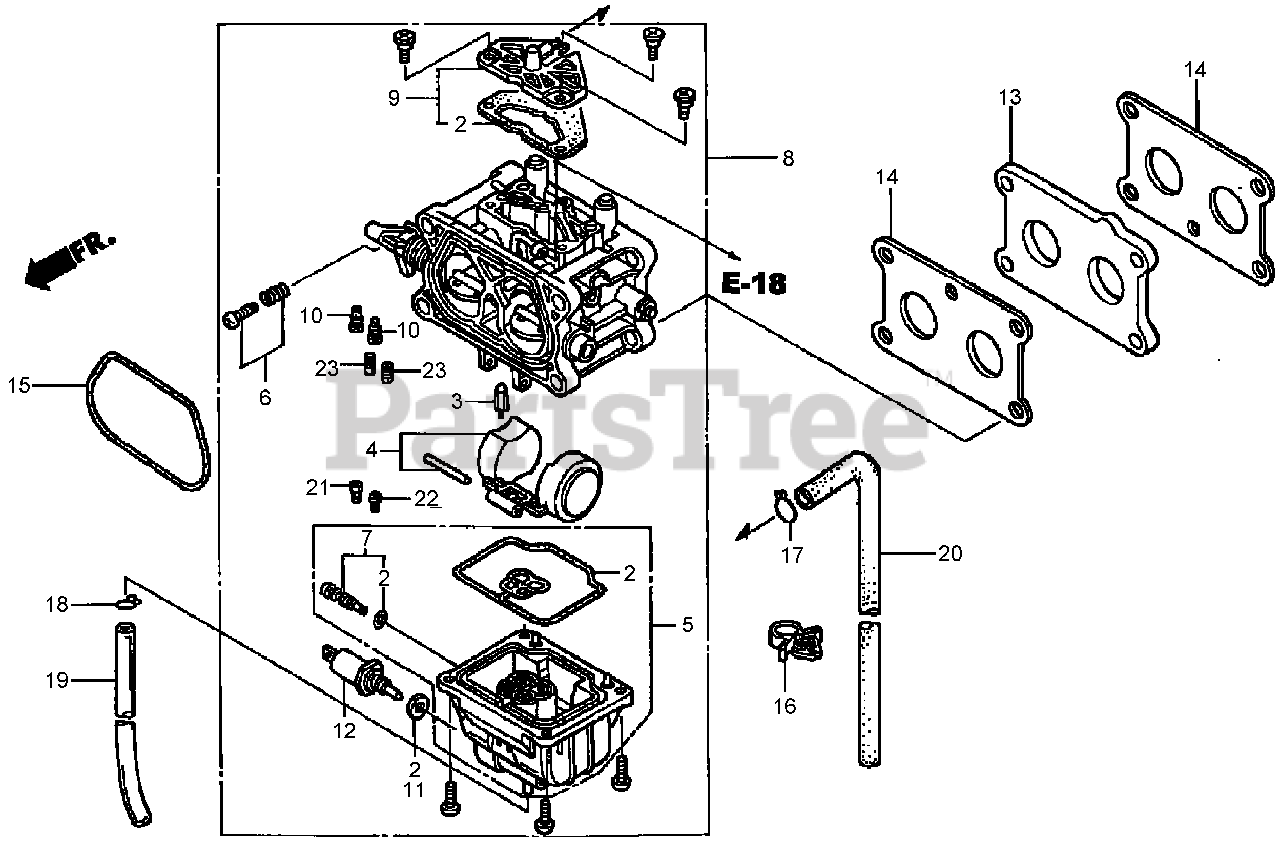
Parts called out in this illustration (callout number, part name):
2	GASKET SET
3	VALVE-FLOAT
4	FLOAT SET
5	FLOAT CHAMBER SET
6	SCREW-SET
7	SCREW-SET, DRAIN
8	CARBURETOR ASM (Up to Engine Serial No. 1014986)
8	CARBURETOR ASM (BW02B C) (Up to Engine Serial No. 1027210)
8	CARBURETOR ASM (BW02B C) (From Engine Serial No.1027211 to 1061017)
8	CARBURETOR ASM (BW02C A) (From Engine Serial No. 1061018)
9	AIR VENT COVER SET
10	CAP
11	GASKET
12	SOLENOID VALVE ASM
13	INSULATOR-CARBURETOR
14	GASKET-INSULATOR
15	GASKET-CLEANER, AIR
16	CLIP-HARNESS, WIRE
17	CLIP-TUBE (B8)
18	CLIP-TUBE (B6.5)
19	HOSE-BULK, VINYL (4X7X8000) (4X7X300)
20	HOSE-BULK, VACUUM (45X1000) (45X400)
21	JET-MAIN (No. 82.5)
21	JET-MAIN (No. 85)
21	JET-MAIN (No. 87.5)
22	JET-MAIN (No. 85)
22	JET-MAIN (No. 87.5)
22	JET-MAIN (No. 90)
23	JET-PILOT (No. 37.5)
